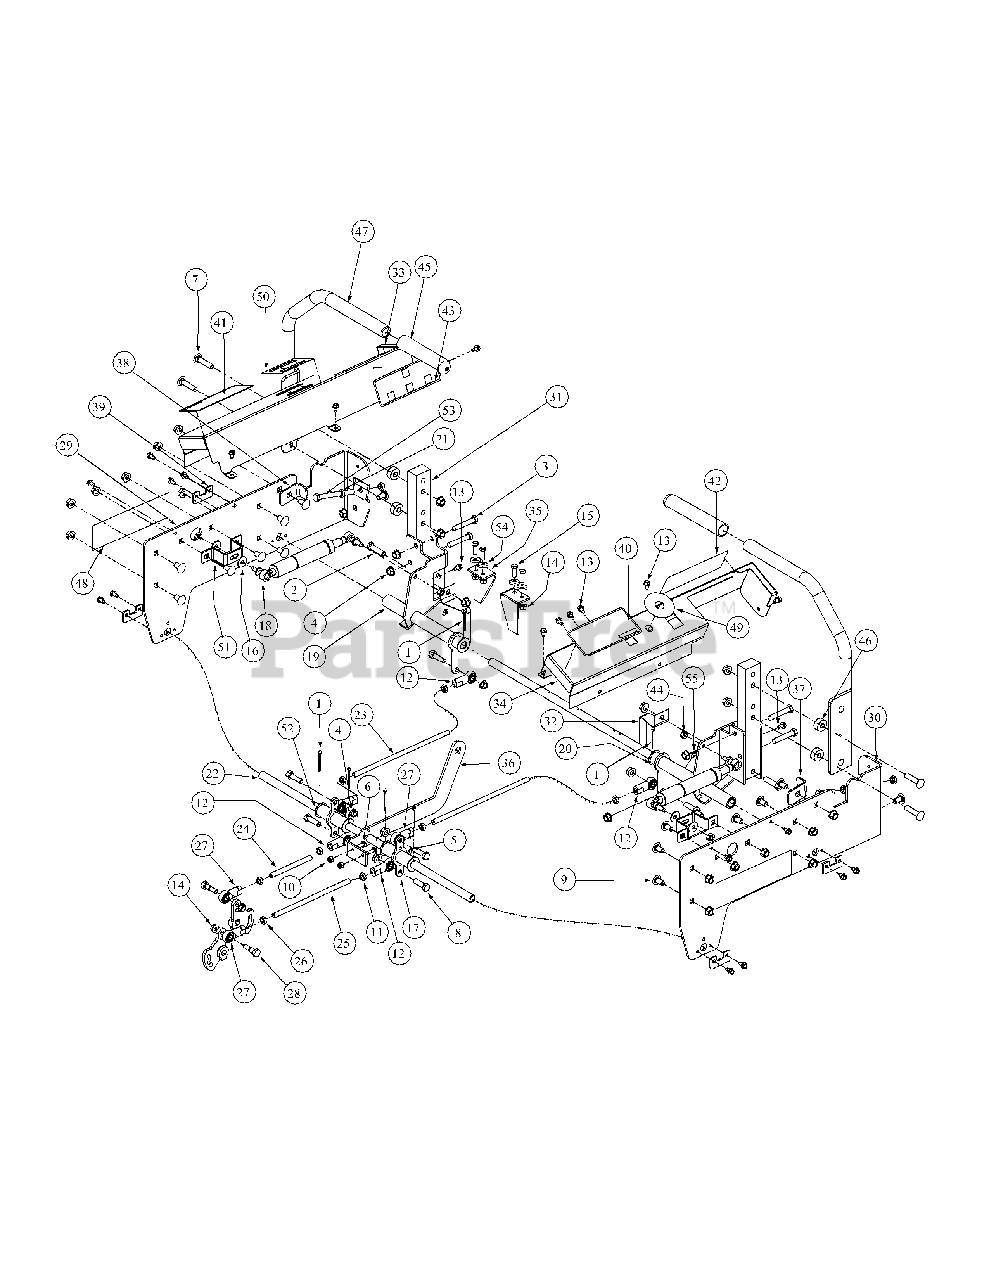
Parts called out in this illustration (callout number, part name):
1	Cotter Pin .125 Dia x 1.0
2	Hex Cap Screw, 3/8-16, 1.50
3	Hex Cap Screw, 3/8-16, 2.5
4	Hex Nut, 3/8-16, Lock Flange
5	Grease Fitting, 1/4-28 x 3/16
6	Hex Cap Screw, 1/4-20, .620
7	Hex Carriage Screw, 3/8-16 x 2
8	Hex Cap Screw, 3/8-16, 1.25
9	Carriage Bolt, 3/8-16 x .75
10	Lock Hex Nut, 1/4-20
11	Hex Jam Nut, 3/8-24
12	B/Joint, 3/8-24, Right Hand Female
13	Screw, TT, 1/4-20, 0.5, Hex Index Washer
14	Nut, Lock, Hex Flange, 5/16-18
15	Hex, Cap Screw, 5/16-18 x 3/4
16	Belle Washer, .325 x .930 x .045
17	Belle Crank Assembly,
17	Bushing
18	Cylinder Return to Neutral
19	Hub Assy, Control LH Bearing
19	Bearings
20	Hub Assy, Control RH Bearing
20	Bearings
21	Nut, 3/8-16, Jam
22	Shaft Mounting Belle Crank
23	Rod Connector 3/8 OD x 10.125
24	Rod Connector, 3/8 OD x 4.28 LG LH
25	Rod Connector, 3/8 OD x 8.06 LG RH
26	Nut, 3/8-24, Jam, LH Third
27	B/Joint, 3/8-24, LH Female
28	Screw, Shoulder Control Rod
29	Side Panel, Control, Left
30	Side Panel, Control, Right
31	Mounting Handle
32	Lever, Safety Switch
33	Control Panel, LH
34	Control Panel, RH
35	Switch Mounting Bracket, Lapbar
36	Link Mounting Control Shaft, Bracket
37	Stop, RH
38	Stop, LH
39	Holder Shaft, Park Brake
40	Decal, Right Hand Console
41	Decal, Left Hand Console
42	Decal Right Hand Control
43	Decal, Left Hand Control
44	Nut, Hex, Center Lock, M8 x 1.2
45	Grip, 1
46	Spacer, .406 ID x 1.00 OD x .38
47	Lapbar Handle, One Position
48	Side Label, MTD Pro
48	Label, MMZ 1848
49	Label, Ignition, 2.5 Diameter
50	Label, Control, Throttle and Choke
51	Bracket Assembly, Mount Dampener
52	Flat Washer, 5/8 Nylon
53	HHCS, 3/8-16, 3.00
54	Flat Washer, 5/16
55	Grease Fitting, 90°, 1/4-28
